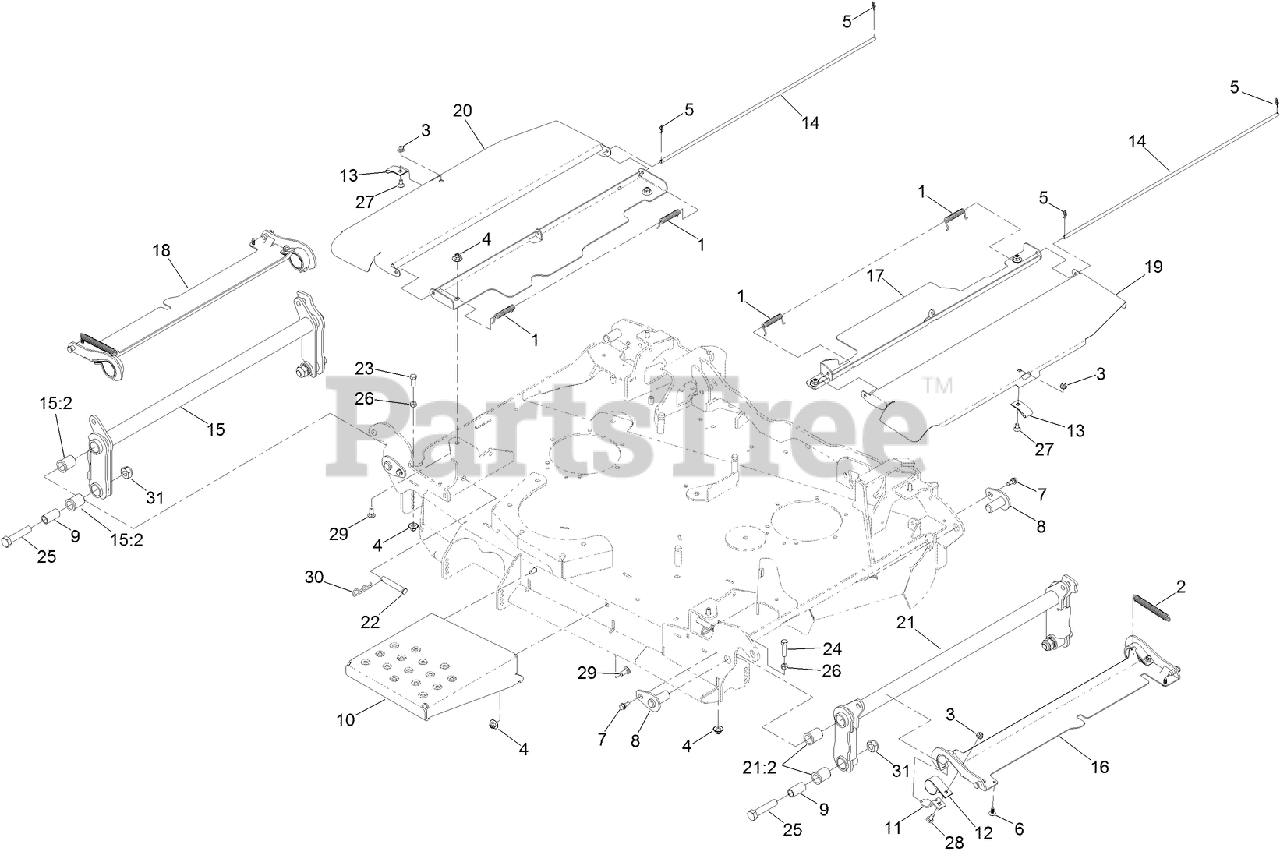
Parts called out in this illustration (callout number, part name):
1	SPRING-TORSION
2	SPRING
3	NUT-HF, NI
4	NUT-FLANGE, NI
5	PIN-COTTER, LOCKING
6	PLUG-PLASTIC
7	SCREW-SHOULDER
8	PIN-DECK
10	PANEL-STEP
11	PLATE-RETAINER, BEARING
12	BEARING-STRAP, NYLON
13	BEARING-STRAP, NYLON
14	COVER-ROD, PIVOT
15	RH FOLD ARM ASM
15:2	BUSHING-FLANGED
16	COVER-WING
17	SHIELD-CENTER, LH
18	SHIELD-CENTER, RH
19	PANEL-SHIELD HINGE, LH
20	PANEL-SHIELD HINGE, RH
21	LH FOLD ARM ASM
21:2	BUSHING-FLANGED
22	PIN-CLEVIS
23	SCREW-HH
24	SCREW-HH
25	SCREW-HH
26	NUT-HEX
27	SCREW-CARR
28	SCREW-CARR
29	BOLT-CARR
30	PIN-HAIR
31	NUT-LOCK
